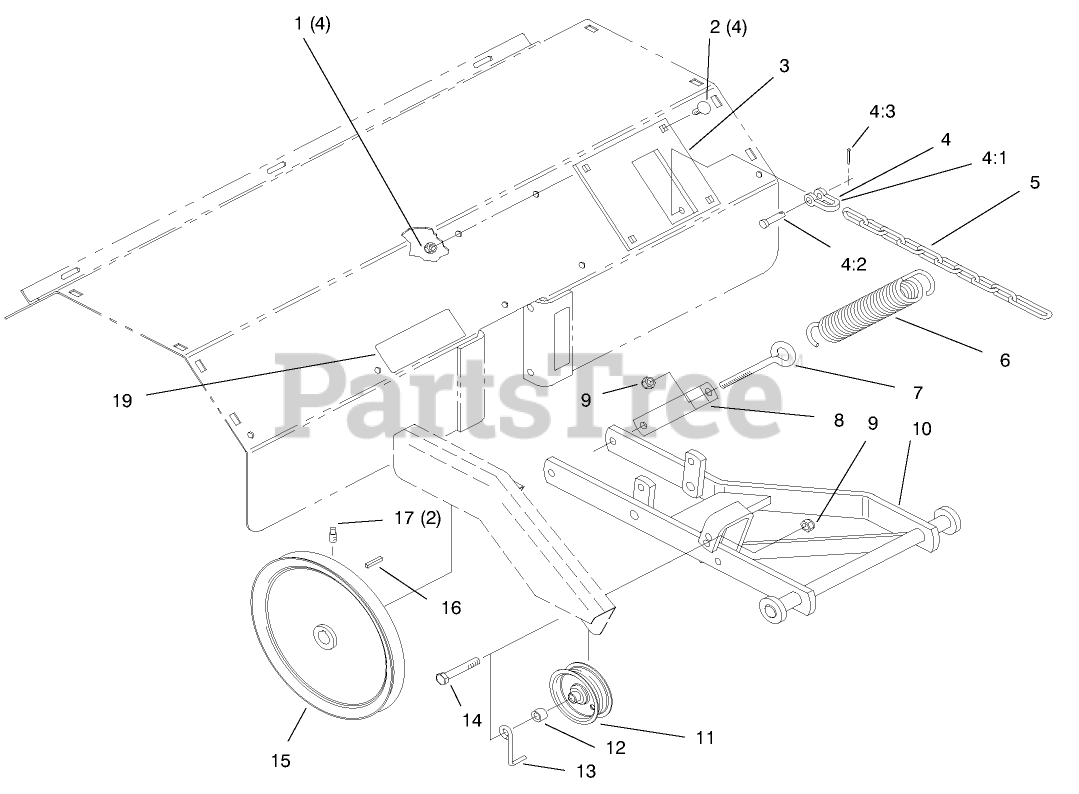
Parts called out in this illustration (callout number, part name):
1	NUT-LOCK, NI
2	BOLT-CARR
3	HITCH ASM
4	CLEVIS ASM
4:1	Clevis
4:2	Clevis Pin
4:3	PIN-COTTER
5	CHAIN-LIFT
6	SPRING
7	EYEBOLT
8	BRACKET - SPRING RED
9	NUT-LOCK, NI
10	HITCH ASM RED
11	PULLEY-IDLER
12	Spacer
13	GUIDE-BELT
14	SCREW-HH
15	PULLEY
16	KEY-STRAIGHT
17	SCREW-SQH
19	DECAL-BELT ROUTING
